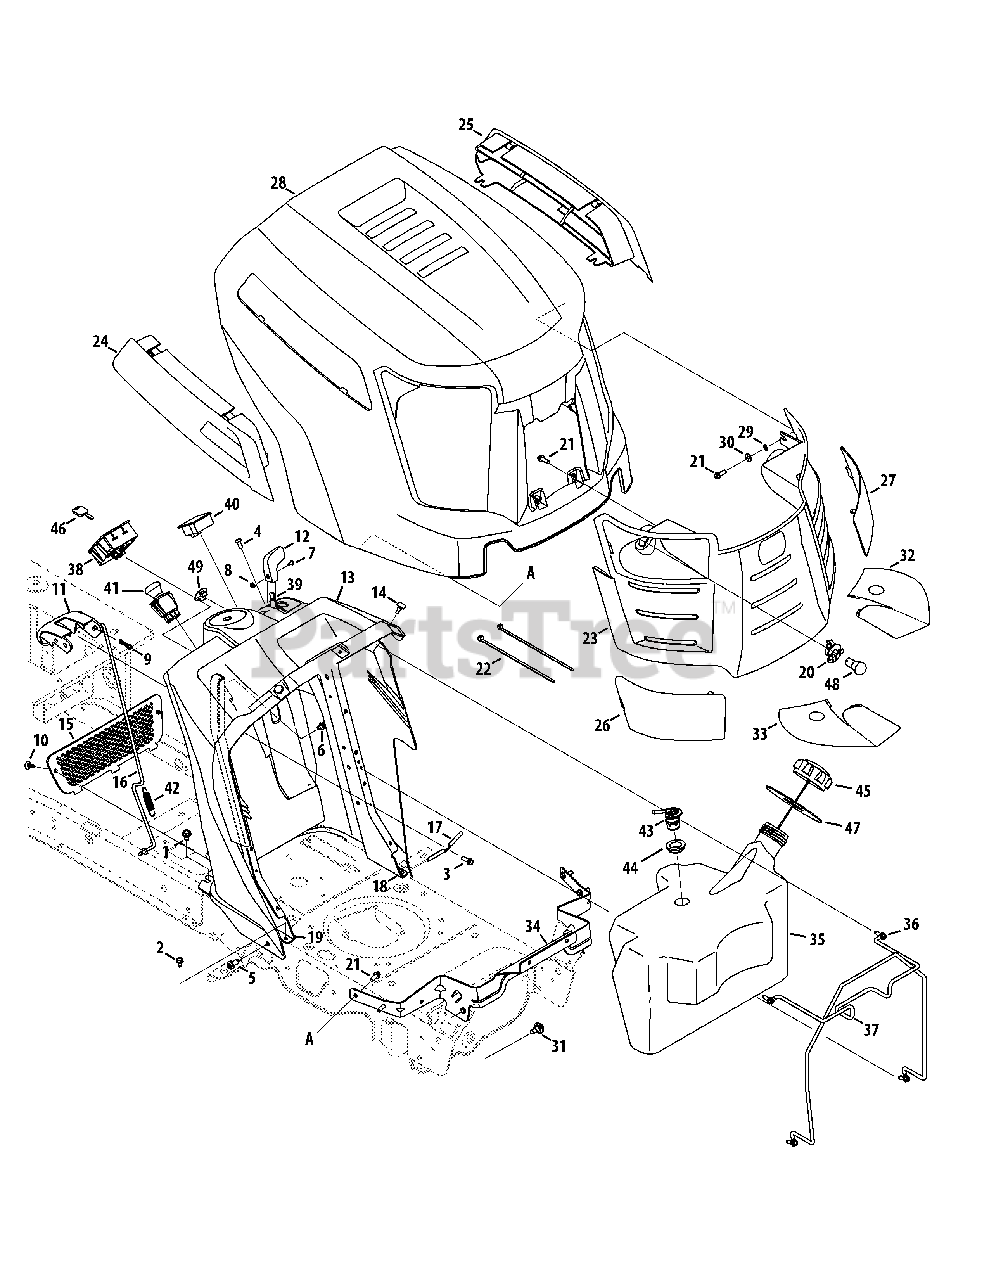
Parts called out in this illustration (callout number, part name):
1	Screw, Self-tapping, 5/16-18, .750
2	Screw, Self-tapping, 1/4-20, 0.500
3	Screw, HL, 1/4-15, 0.750
4	Screw, Ab, 1/4-14, 0.625,
5	Screw, Self-tapping, 5/16-18, 0.750,
6	Screw, Self-tapping, 1/4-20 x .625
7	Screw, Mach, #8-32, 0.375
8	Nut, Hex, #8-32
9	Pin, Cotter, Bow-Tie 72
10	Clip, Ratchet, .250 Dia
11	Lever, Dash, Cruise/Brake
12	Knob, Throttle
13	Dash Panel, A-Style, Man PTO
14	Bumper, .62 Dia X .3
16	Rod, Control, Latch Cub
17	Rod, Lever, Bent
18	Support, Dash, Plate LH
19	Support, Dash, Plate RH
20	Socket, Lamp
21	Screw, 1/4 Dia, .750
22	Tie, Cable, Push Mount 7.5 Lg
23	Grille Ass’y (Incl. 26, 27, 32 & 33)
24	Scoop, Hood, RH A-Style
25	Scoop, Hood, LH A-Style
26	Lens, Hood, RH A-Style
27	Lens, Hood, LH A-Style
28	Hood, A-Style
29	Washer, Lock, 1/4, External
30	Washer, Flat, .271, .630, .065
31	Screw, Shoulder, .43x.29, 5/16-18
32	Reflector, Cub A Style, LH
33	Reflector, Cub A Style, RH
34	Bracket, Pivot, Hood A-Style
35	Tank, Fuel, 3.30 Gal.
36	Screw, Self-tapping, 1/4-20, .75
37	Rod, Support, Fuel Tank
38	Module Switch, Ignition
39	Cable, Throttle/Choke, 38"
40	Meter, Indicator
41	Switch, Electric PTO, Yellow
42	Spring, .500 Dia. x 2.733
43	Valve, Rollover Grommet
44	Grommet, Rubber, 23.0 ID
45	Cap, Fuel
46	Key, Ignition
47	Gasket, Fuel Tank
48	Lamp, 12v
49	Plug, Choke
